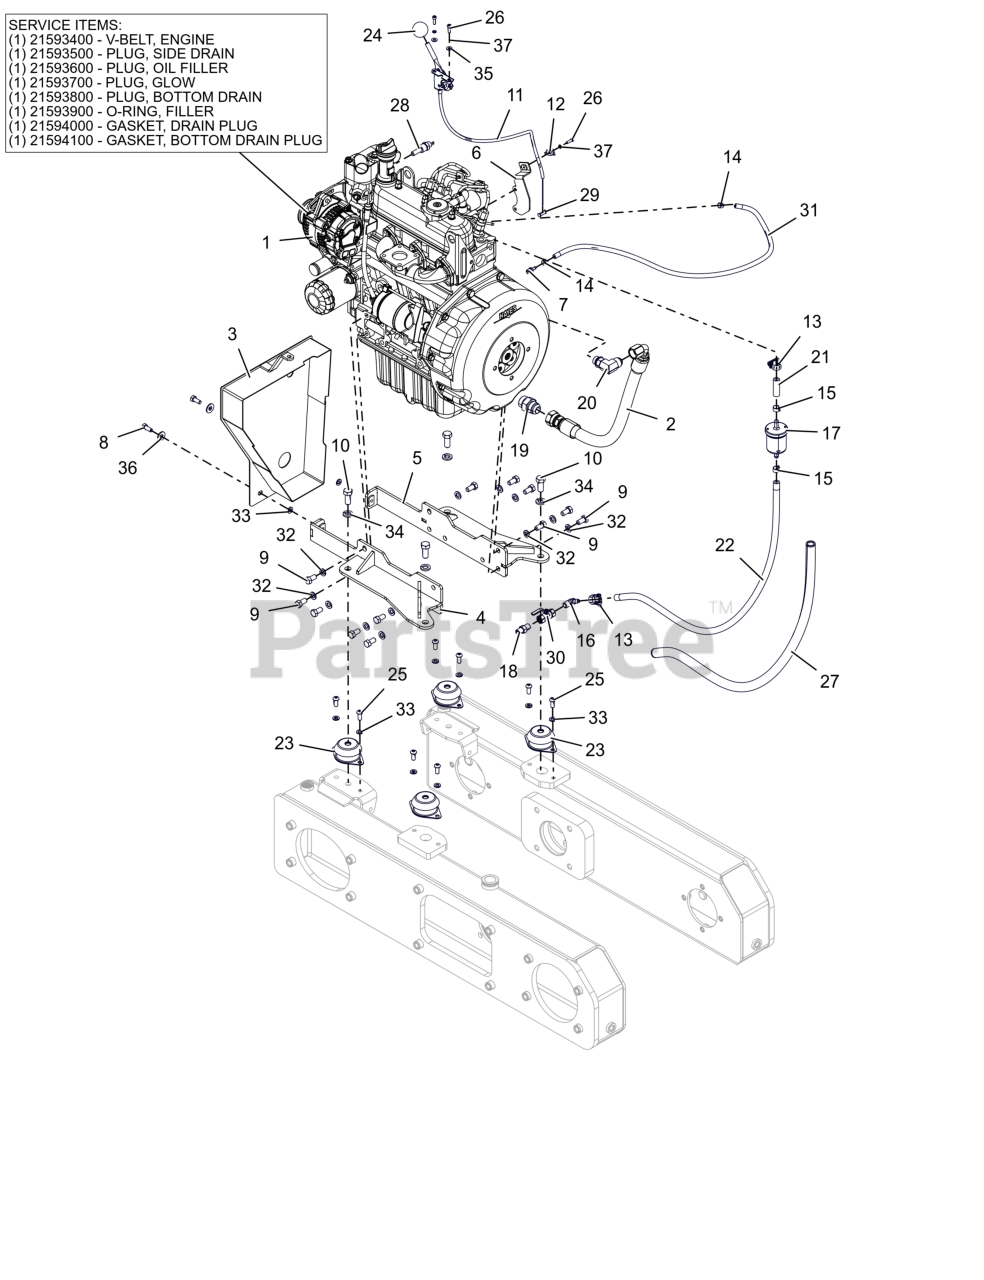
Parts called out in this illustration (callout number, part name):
1	ENGINE, KUBOTA-D1105
1	V-BELT ENGINE
1	PLUG, SIDE DRAIN
1	PLUG, OIL FILLER
1	PLUG, GLOW
1	PLUG, BOTTOM DRAIN
1	O-RING, OIL FILLER
1	GASKET, SIDE DRAIN PLUG
1	GASKET, BOTTOM DRAIN PLUG
2	HOSE, HYD .625" X 45.00" LG
3	COVER, ENGINE (BLACK)
4	MOUNT, ENGINE - RH (BLACK)
5	MOUNT, ENGINE - LH (BLACK)
6	MOUNT, CABLE (BLACK)
7	ADAPTOR, FUEL - .13NPTX.19 HOSE
8	BLT,HEX .31-18X.75 G5 ZCC
9	BLT-HEX M10 X 1.25X20 YWZC
10	BLT-BRAKE, M12 X 1.75X30
11	CABLE, THROTTLE
12	CLAMP, CABLE
13	CLAMP-HOSE WRM .44/.78X.53 F06
14	CLAMP-HOSE, SPRING .188
15	CLAMP, HOSE SPRING .313
16	ELBOW, FUEL - .25NPTX.312 HOSE
17	FILTER, FUEL
18	FITTING, HYDRAULIC 5404 04-04
19	FITTING, HYDRAULIC 6400 12-12
20	FITTING, HYDRAULIC 9059 08-10
21	GAS LINE, 5/16" ID (PRESSURE)
22	GAS LINE, 5/16" ID (PRESSURE)
23	ISOLATOR, ENGINE
24	KNOB, BALL -.375-24
25	SCR-SKH .31-18X.75 BTNHD YWZC
26	SCR, SKH 10-32X.625 GR5 ZCC
27	SPLIT TUBING-22"
28	SWITCH, TEMPERATURE
29	SWIVEL, CABLE
30	VALVE, BALL - .25" NPT
31	HOSE, .188 30R7 BULK
32	WSHR,LK-M10 ZCC
33	WSHR,LK-REG .312X.078 ZCC
34	WSHR,LK-REG 0.502 X 0.125 ZCC
35	WSHR, FLT .219X.500X.049 ZCC
36	WSHR,FLT .375X.875X.083 ZCC
37	@WSHR-LK #10X.047 REG YWZC
